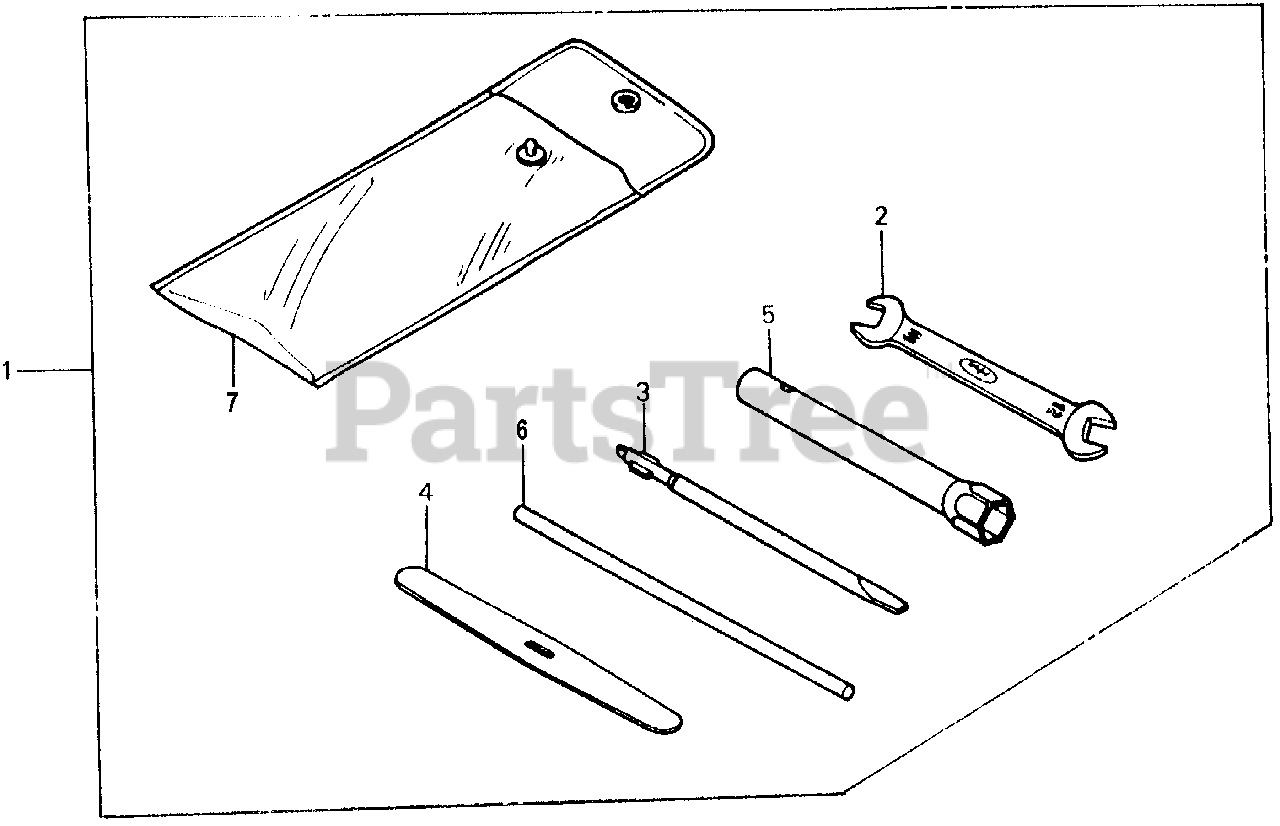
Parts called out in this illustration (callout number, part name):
2	WRENCH (10X12) (OPEN END)
3	SCREWDRIVER 3, STRAIGHT SLOT (NO.2)
4	LEVER, TIRE
5	WRENCH, BOX (P21)
6	BAR A, HANDLE
